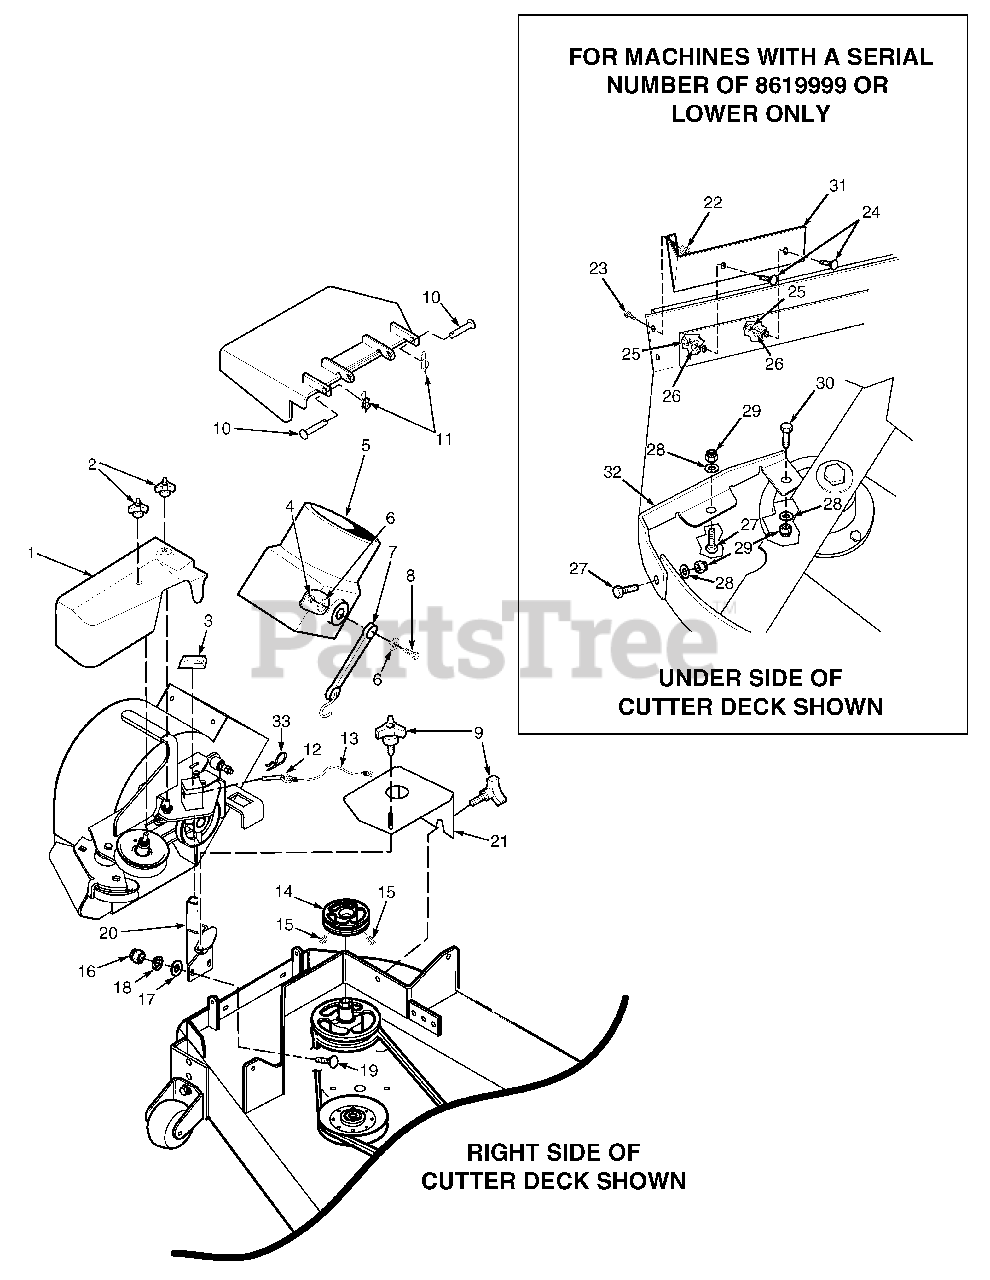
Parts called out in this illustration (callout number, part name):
1	Belt Cover, GC-STT - 52"
1	Belt Cover, GC-STT - 61"
2	Wingnut, Plastic 3/8" Small
3	Cap, Square Vinyl
4	Nut, Elastic Stop 1/4-20
5	Adapter w/Strap
6	Flatwasher, 1/4-.312 x .750 x .065
7	Rubber Strap 7-3/4"
8	Bolt, Hex Head 1/4-20 x 1-1/4"
9	Knob W/Stud, 3/8-16 x 1-1/4"
10	Clevis Pin, 5/16 x 1-1/2"
11	Pin, Rue Cotter 5/16 Dia.
12	Pin, Ring 1/2 x 2-1/4"
13	Lanyard
14	Pulley, 4-1/2" for 52" Deck
14	Pulley, 5-1/2" for 61" Deck
15	Setscrew, 5/16-18 x 3/8"
16	Nut, Elastic Stop 1/2-13
17	Flatwasher, 1/2-.531 x 1.062 x .095
18	Lockwasher, 1/2"
19	Bolt, Hex Head 1/2-13 x 1-1/2" Grade 5
20	Mounting Post Weldment, Blower - 52"
20	Mounting Post Weldment, Blower - 61"
21	Belt Cover, - 52"
21	Belt Cover Assembly, - 61" w/Cap
22	Nut, Serrated Flange 1/4-20
23	Bolt, Hex Head 1/4-20 x 3/4"
24	Bolt, Carriage 3/8-16 x 1"
25	Nut, Elastic Stop 3/8-16
26	Flatwasher, 3/8-.391 x .938 x .105
27	Bolt, Hex Head 5/16-18 x 1"
28	Flatwasher, 5/16-.375 x .875 x .083
29	Nut, Elastic Stop 5/16-18
30	Bolt, Hex Head 5/16-18 x 1-3/4"
31	Baffle, 52"
31	Baffle, 61"
32	Baffle, 52" Deck
32	Baffle, 61" Deck
33	Hair Pin Cotter, .177 x 3-1/4"
